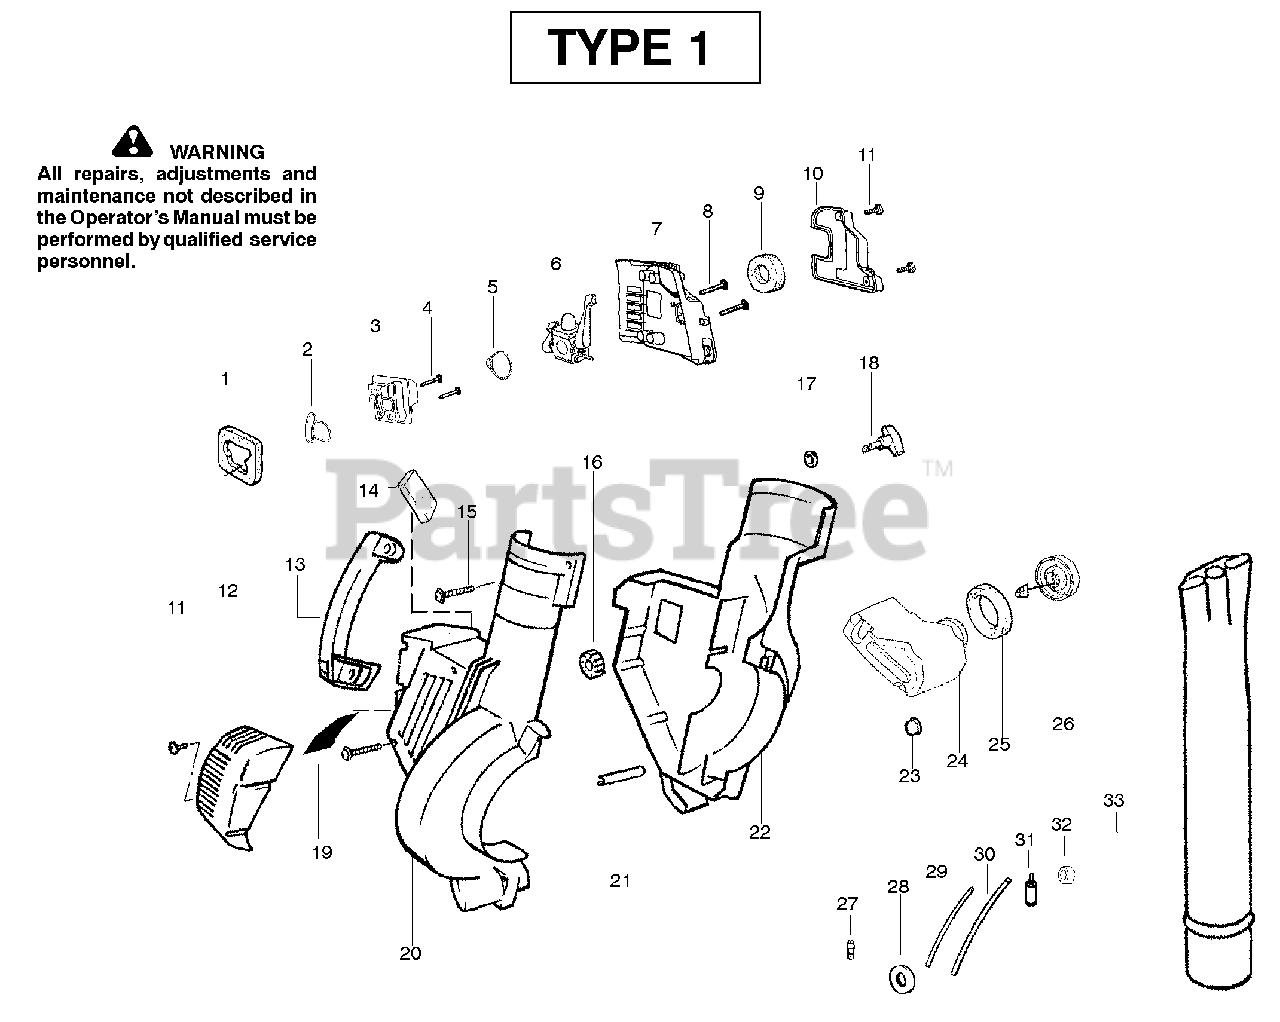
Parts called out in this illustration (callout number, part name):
1	Air Dam (kit)
2	Gasket-Adapter (kit)
3	Carburetor Adaptor
5	Gasket-Carburetor (kit)
6	Kit-Carb Ass'y. Zama-(C1Q-W11C)
6	Kit-Carb Ass'y. Walbro-(WT-606)
8	Screw-Carb.
9	Filter-Air
10	Cover-Air Filter
12	Guard-Muffler
14	Foam - 71.12mm (kit)
16	Isolator
18	Knob-Blower
19	Tape-Reflector (kit)
20	Shroud-RH
21	Guide-Starter Rope
22	Shroud-LH
23	Isolator-Crankcase
24	Assy-Fuel Tank
25	Gasket-Fuel Tank
26	Fuel Cap w/Retainer
27	Fitting-Fuel Line
28	Grommet-Shroud
29	Kit-Line Carb/Purge
30	Kit-Line Tank/Purge
31	Assy-Fuel Pick-up
32	Grommet-Fuel line (kit)
33	Tube-Blower
